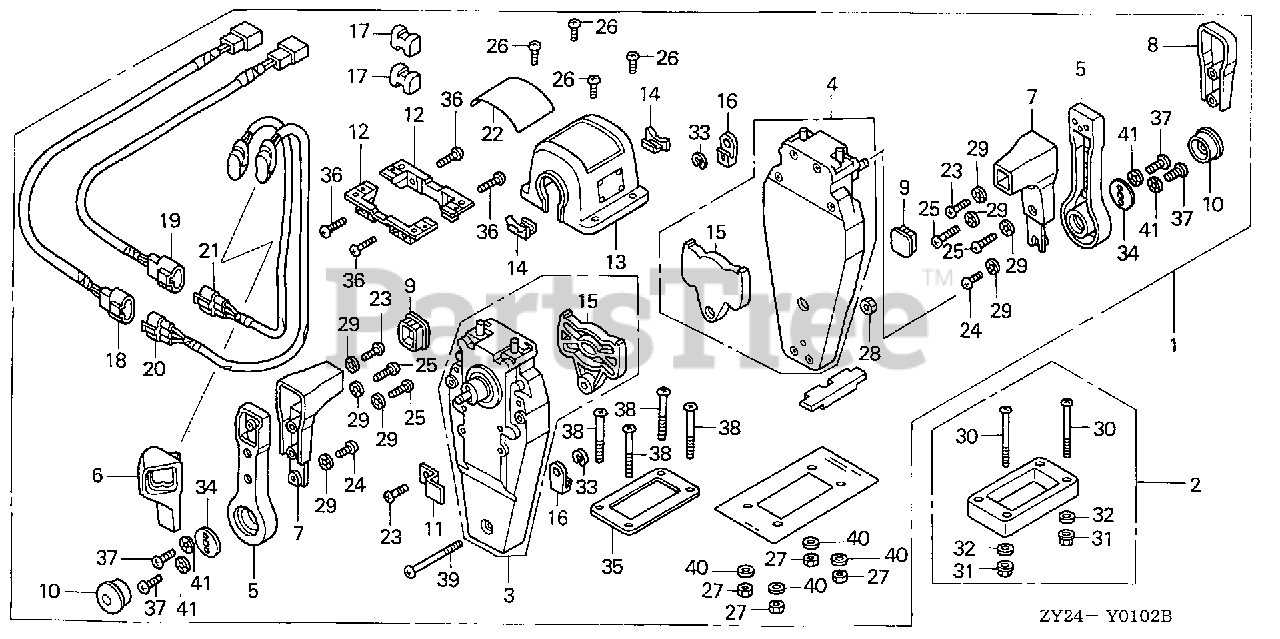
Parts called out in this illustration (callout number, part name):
1	BOX KIT, REMOTE CONTROL (TOP MOUNT DUAL)(R)
2	SPACER KIT, REMOTE CONTROL BOX (TOP MOUNT DUAL)
3	HOUSING ASSY., L. (INNER) (TOP MOUNT)
4	HOUSING ASSY., R. (INNER) (TOP MOUNT)
5	HANDLE, REMOTE CONTROL
6	COVER, L. GRIP
7	GRIP, REMOTE CONTROL HANDLE
8	COVER, DUAL GRIP
9	CAP, GRIP
10	BUTTON, THROTTLE
11	PLATE, CABLE CLAMP
12	BRACKET, REMOTE CONTROL HOUSING
13	HOUSING, DUAL REMOTE CONTROL BOX
14	HOUSING, LEAD
15	PLATE, DWELL
16	TERMINAL, CABLE
17	SPACER, CABLE CLAMP
18	SUB-HARNESS ASSY., POWER TRIM-TILT (A)
19	SUB-HARNESS ASSY., POWER TRIM-TILT (B)
20	SWITCH ASSY., POWER TRIM-TILT (A)
21	SWITCH ASSY., POWER TRIM-TILT (B)
22	MARK, REMOTE CONTROL (DUAL)
23	SCREW, PAN (5X16)
24	SCREW, PAN (5X10)
25	SCREW, PAN (5X20)
26	SCREW, PAN (4X10)
27	NUT, HEX. (5MM)
28	NUT, HEX. (5MM)
29	WASHER, LOCK (5MM)
30	SCREW, PAN (5X65)
31	NUT, FLANGE (5MM)
32	WASHER, PLAIN (5MM)
33	E-RING (6MM)
34	PLATE, HANDLE
35	GASKET, DUAL
36	SCREW, PAN (5X18)
37	SCREW, PAN (6X18)
38	SCREW, PAN (5X40)
39	SCREW, PAN (5X55)
40	WASHER, LOCK (6MM)
41	WASHER, PLAIN (5MM)
